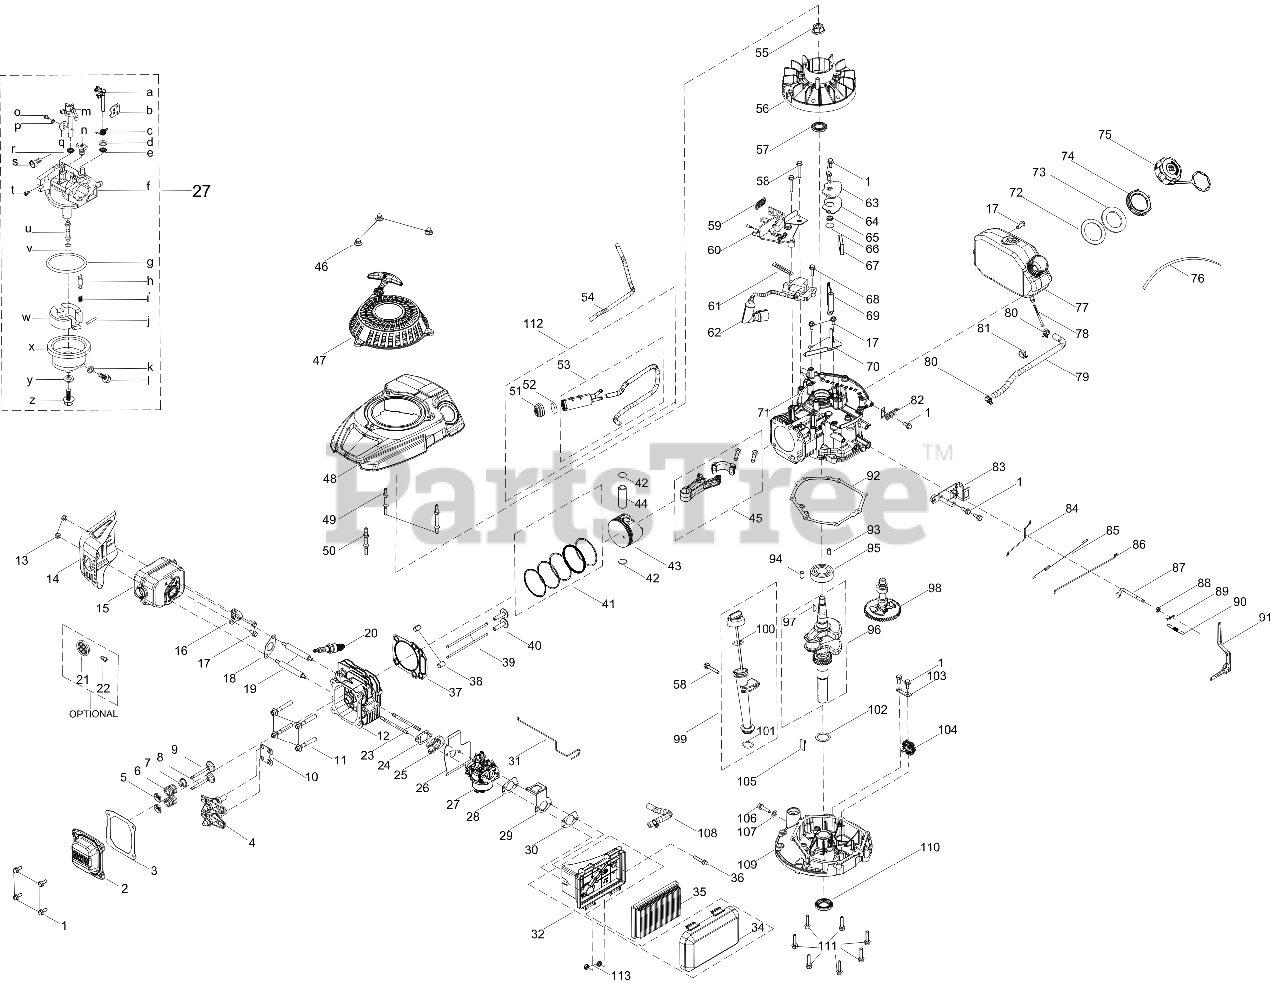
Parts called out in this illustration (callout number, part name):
1	BOLT M6-1 x 14 GR8.8
2	VALVE COVER
3	VALVE COVER GASKET
4	ROCKER ARM ASSEMBLY
5	VALVE SPRING RETAINER
6	VALVE SPRING
7	INTAKE VALVE SEAL
8	EXHAUST VALVE
9	INTAKE VALVE
10	PUSH ROD GUIDE
11	BOLT-M8 x 54
12	CYLINDER HEAD
14	MUFFLER SHIELD
15	MUFFLER ASSEMBLY
16	THERMOSTAT
17	BOLT M6-1 x 12 GR8.8
18	MUFFLER GASKET
19	STUD M6-1 x 95
20	SPARK PLUG
21	SPARK ARRESTOR
22	SCREW M3.5 x 9.5
23	CARBURETOR STUD-M6 x 87
24	CARBURETOR INSULATOR GASKET
25	CARBURETOR INSULATOR
26	CARBURETOR GASKET
27	CARBURETOR ASSEMBLY
28	CHOKE TEMP CONTROL BRACKET GSKT
29	CHOKE TEMP CONTROL BRACKET
30	AIR FILTER BASE GASKET
31	CHOKE TEMP CONTROL LINKAGE
32	AIR FILTER HOUSING ASSEMBLY
34	AIR FILTER COVER
35	AIR FILTER
36	BOLT-M6-1 x 30 GR8.8
37	CYLINDER HEAD GASKET
40	TAPPET
41	PISTON RING SET
42	SNAP RING-PISTON PIN
43	PISTON
44	PISTON PIN
45	CONNECTING ROD ASSEMBLY
46	ACORN NUT
47	RECOIL STARTER ASSEMBLY
48	ENGINE SHROUD
49	STARTER/SHROUD REAR STUD
50	STARTER/SHROUD FRONT STUD
51	CARBON CANISTER FILTER CAP
52	CARBON CANISTER FILTER
53	CARBON CANISTER
54	CARBON CANISTER PURGE HOSE
55	FLYWHEEL NUT
56	FLYWHEEL
57	CRANKSHAFT SEAL
58	BOLT M6-1 x 35 GR8.8
59	ENGINE BRAKE SPRING
60	ENGINE BRAKE ASSEMBLY
61	FLEXIBLE CLAMP
62	IGNITION COIL
63	BREATHER COVER PLATE
64	BREATHER GASKET
65	BREATHER VALVE SPRING
66	BREATHER VALVE
67	BREATHER SCREEN
68	BOLT M6-1 x 20 GR8.8
69	AIR VANE
70	AIR VANE BRACKET
72	FUEL TANK LOWER GROMMET
73	FUEL TANK UPPER GROMMET
74	FUEL TANK NUT
75	FUEL CAP ASSEMBLY
76	CABLE TIE - 3 x 150
78	FUEL FILTER
80	HOSE CLAMP
81	FUEL LINE SUPPORT CLAMP
82	FLEXIBLE CLAMP
83	COMPONENT BRACKET
84	CHOKE LINKAGE
85	THROTTLE LINKAGE SPRING
86	THROTTLE LINKAGE
87	GOVERNOR ARM SHAFT
88	GOVERNOR SEAL
89	COTTER PIN
90	GOVERNOR SPRING
91	GOVERNOR ARM ASSEMBLY
92	CRANKCASE COVER GASKET
93	DOWEL PIN
94	DOWEL PIN
96	CRANKSHAFT ASSEMBLY
97	FLYWHEEL KEY
98	CAMSHAFT ASSEMBLY
99	OIL DIPSTICK ASSEMBLY
100	O-RING
102	THRUST WASHER
103	GOVERNOR GEAR MOUNTING PLATE
104	GOVERNOR GEAR/SHAFT ASSEMBLY
105	OIL RETURN SEAL
106	OIL DRAIN PLUG
107	WASHER
108	BREATHER HOSE
109	CRANKCASE COVER
110	LOWER CRANKSHAFT SEAL
111	BOLT-M6-1 x 28 GR8.8
112	CARBON CANISTER
Z	BOLT M8-1 x 10
